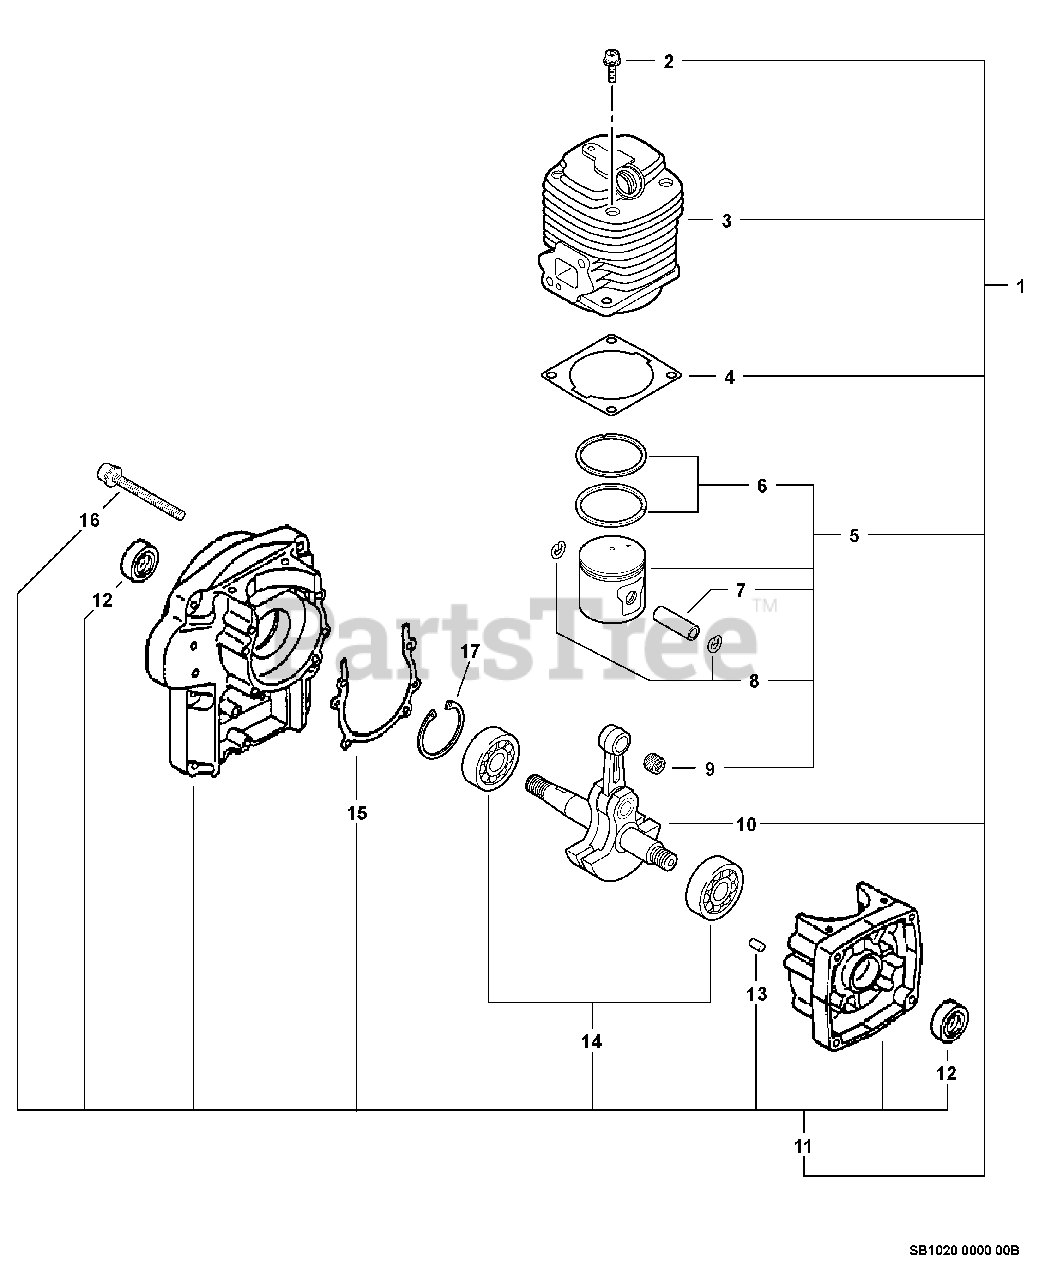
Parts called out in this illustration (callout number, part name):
1	SHORT BLOCK PB-6000
2	BOLT 5×22
3	CYLINDER
4	GASKET, CYLINDER
5	PISTON KIT
6	RING, PISTON
7	PIN, PISTON
8	RING, SNAP 8
9	BEARING, NEEDLE 10
10	CRANKSHAFT ASSY
11	CRANKCASE KIT
12	SEAL, OIL
13	PIN, LOCATING 4×8
14	BEARING, BALL 6202
15	GASKET, CRANKCASE
16	BOLT 5×40
17	RING, SNAP 35
